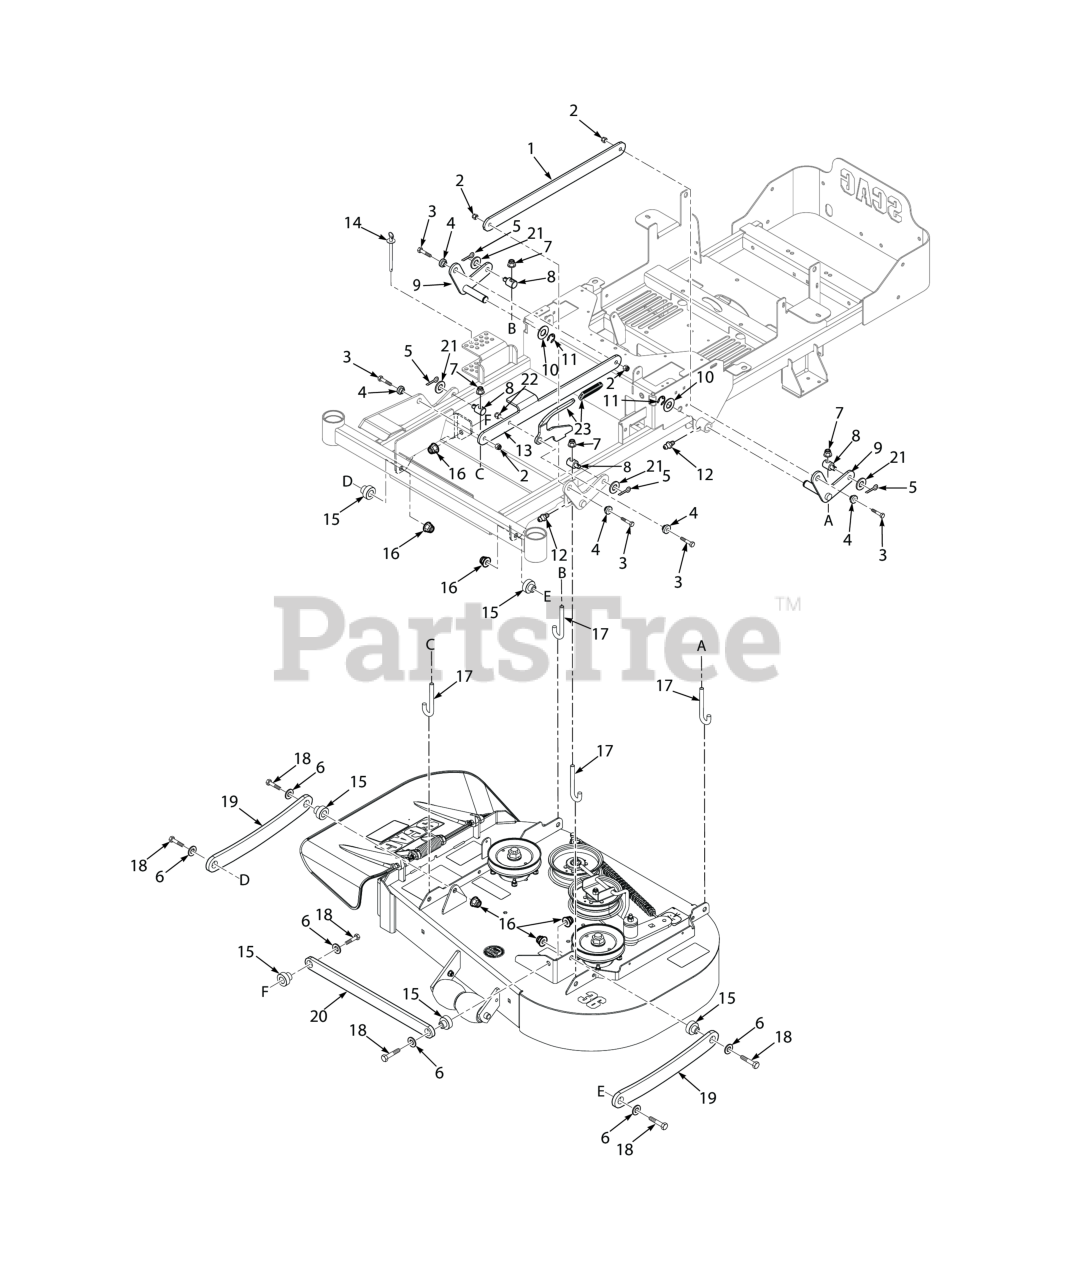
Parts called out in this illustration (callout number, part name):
1	Link, Deck Lift - LH
2	Nut, Flange Elastic Stop Nut, 3/8-16
3	Bolt, Hex Head 3/8-16 x 1-1/4", Kawasaki FX / FS
4	BUSHING, SPEED ADJUSTMENT LEVER
5	Pin, Cotter 3/16 x 1.0"
6	Flatwasher, 1/2 - .531 x 1.062 x .095
7	HEX LOCKNUT, ELASTIC STOP, 1/2-13
8	Joint, Swivel
9	Lift Bellcrank Weldment
10	Flatwasher, 3/4 (.766 x 1.250 x .060)
11	RETAINING RING, 3/4" EXTERNAL "E"
12	GREASE FITTING, STR. 1/4-28 SELF TAP.
13	Link, Deck Lift - RH
14	Pin Assembly, Deck Height
15	Bushing, Deck Lift
16	Nut, Elastic Stop 1/2-13, (STT-52 & STTII-52)
17	Rod, Deck Lift
18	Bolt, Hex Head 1/2-13 x 1-3/4"
19	Pull Arm, Deck
20	Lateral Link
21	Flatwasher, 5/8" (.656 x 1.312 x .095")
22	HEX NUT, ELASTIC STOP LOCK, 3/8-16
23	Lever Assembly (incl. Grip)
